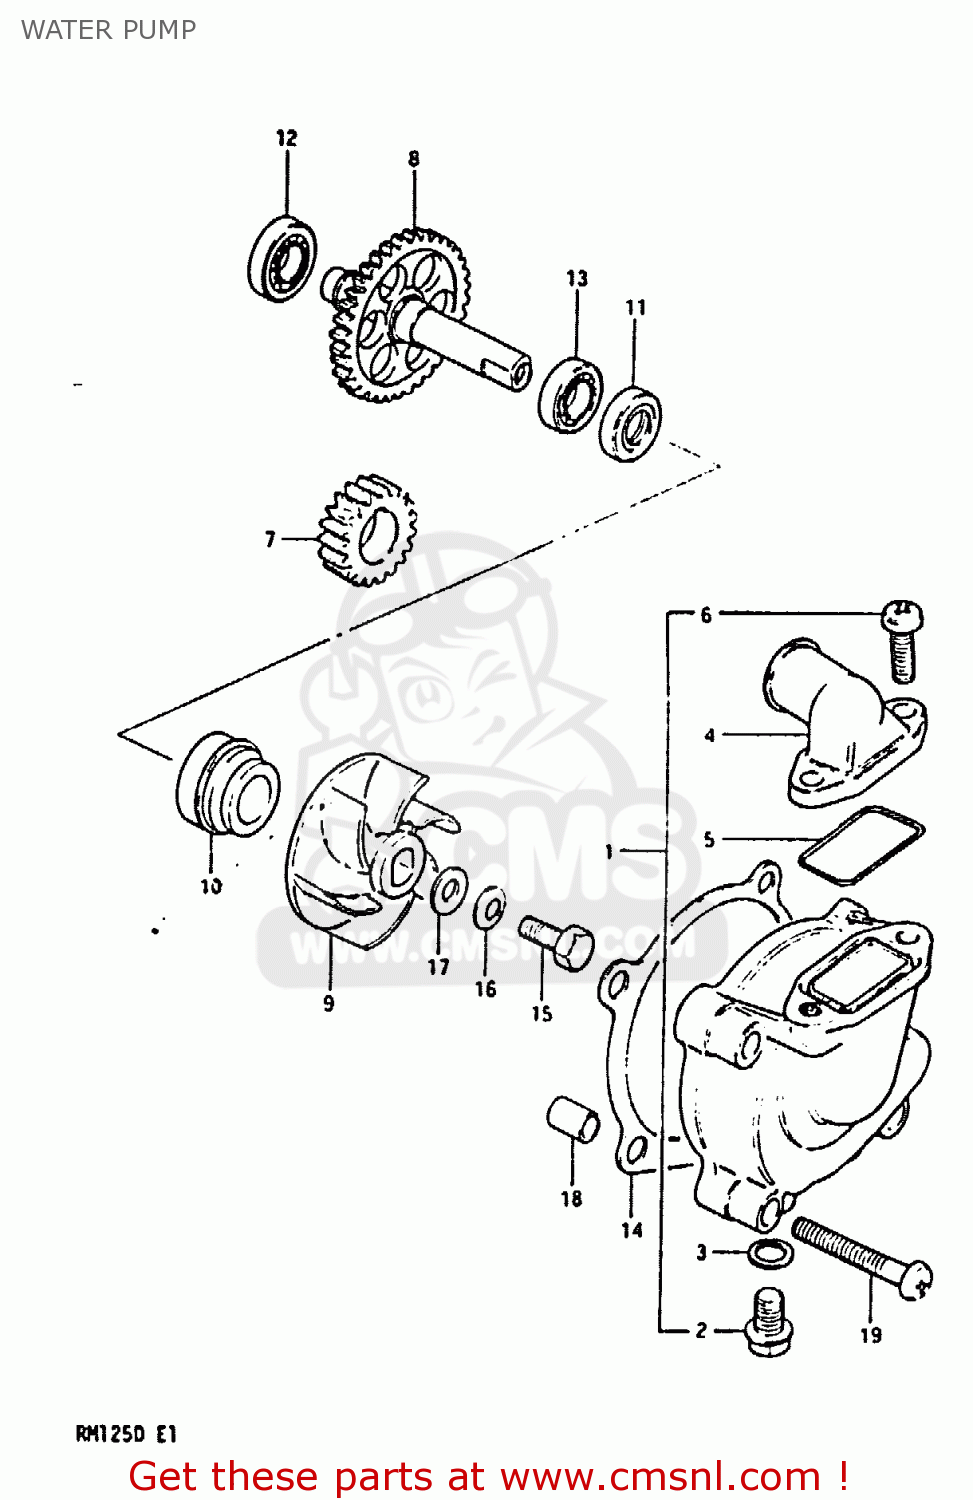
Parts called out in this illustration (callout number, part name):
1	CASE
2	BOLT,DRAIN
3	GASKET,DRAIN (NAS)
4	CONNECTOR
5	O RING,WATER PUMP CONNECTOR
6	SCREW
7	GEAR,WATER PUMP DRIVE
8	GEAR,WATER PUMP DRIVEN(NT:36)
9	IMPELLER,WATER PUMP
10	SEAL,WATER PUMP SHAFT
11	SEAL,OIL(10X21X5)
12	BEARING(10X22X6)
13	BEARING
14	GASKET,WATER PUMP CASE (MCA)
15	BOLT(6X13)
16	WASHER
17	GASKET (NAS)
18	PIN
19	SCREW
